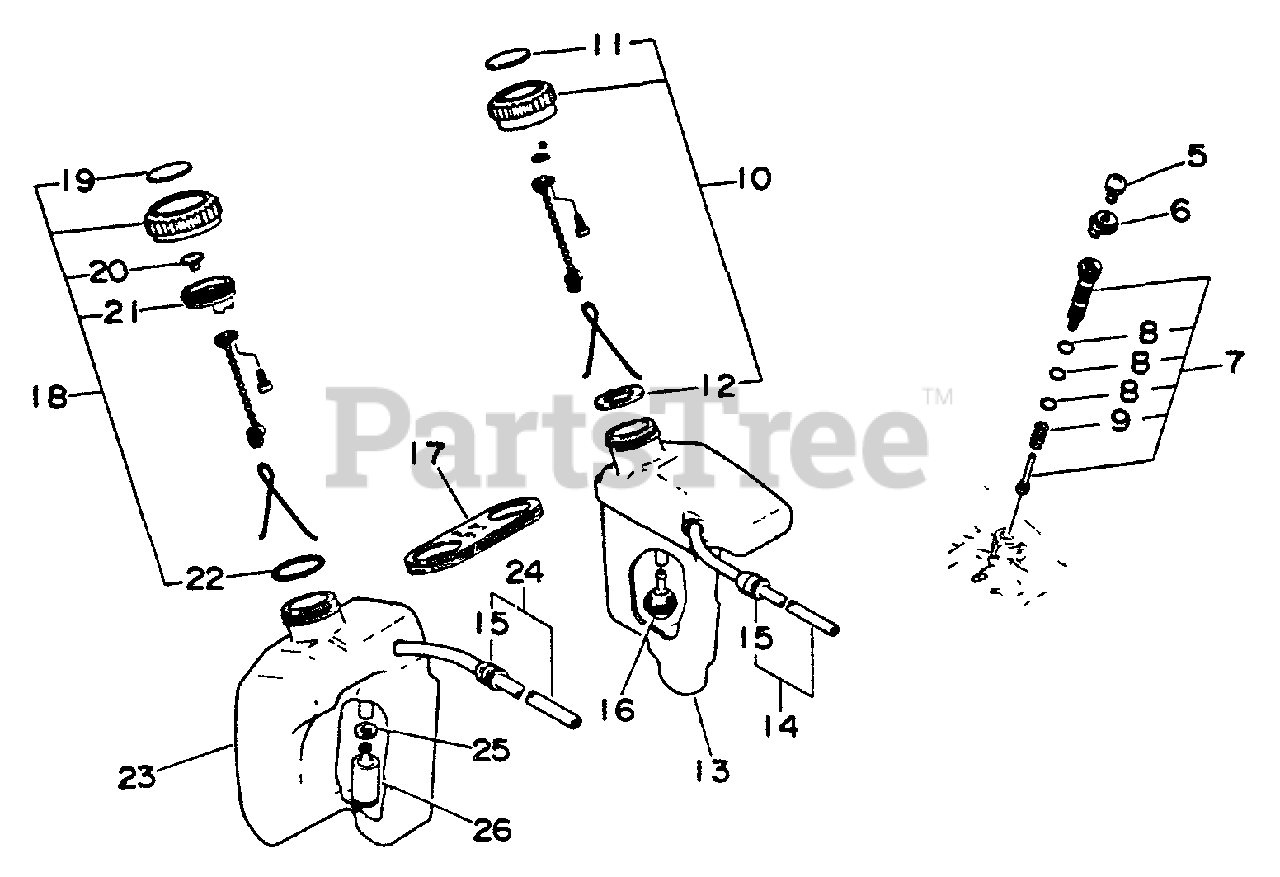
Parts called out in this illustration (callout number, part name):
5	SCREW - 5X10
6	LOCKWASHER
7	AUTO-OILER ASSY
8	O-RING - 5
10	CAP ASSY
11	LABEL - CHAIN OIL
12	GASKET, CAP
13	TANK, OIL
14	OIL PIPE KIT
16	FILTER, OIL
17	CONNECTOR
18	CAP ASSY
19	LABEL - FUEL MIX
21	HOLDER, VENT
22	O-RING - 22
23	TANK, FUEL
24	FUEL PIPE KIT
25	WASHER - 5
26	FILTER, FUEL
